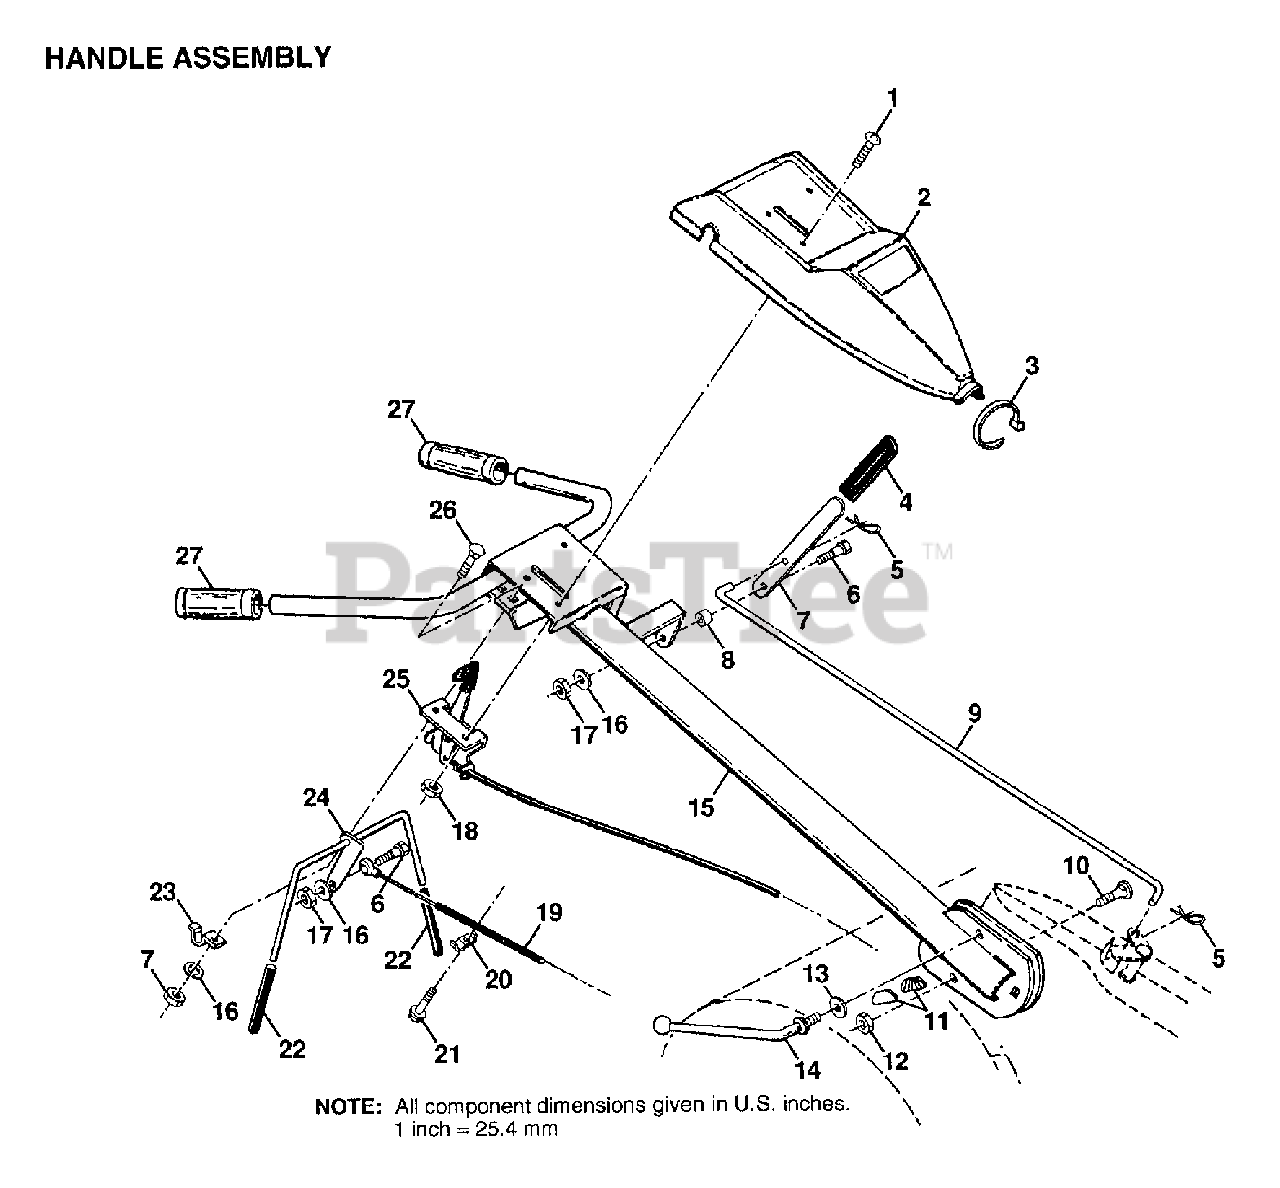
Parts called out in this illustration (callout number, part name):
1	SCREW
2	"PANEL,CONT TI"
3	TIE CABLE CRT
4	GRIP T
5	RETAINER M
6	SHOULDER BOLT ST
7	SHIFT HANDLE CRT
8	GROMMET CRT
9	SHIFT ROD CRT
10	BOLT D
11	LOCK CRT
12	LOCKNUT
13	WASHER CRT
14	LEVER LOCK CRT
16	LOCKWASHER
19	CABLE.CLUTCH.CRT
20	CONDIUT CLIP T
22	GRIP BAR CRT
24	"ASSY CONTROL, BAR"
25	"CONT,THROTTLE"
26	BOLT
